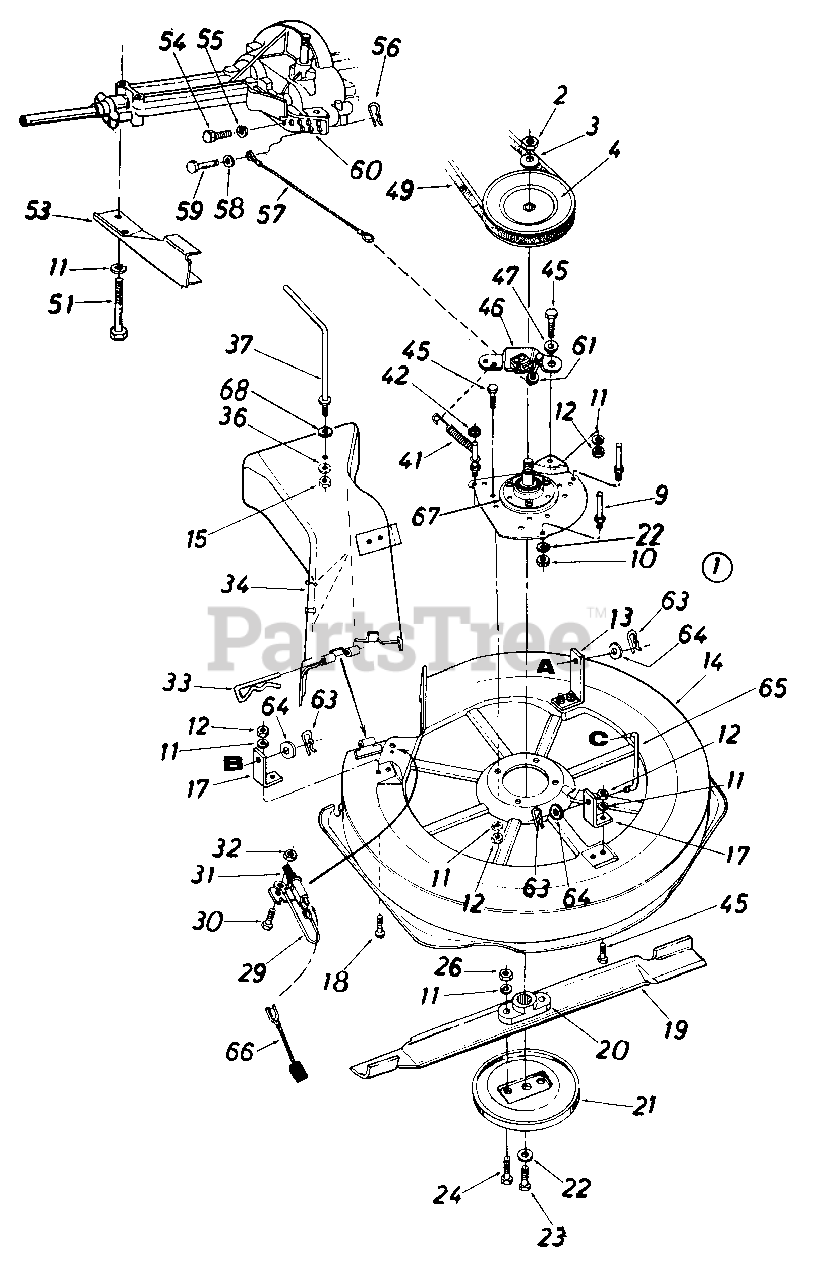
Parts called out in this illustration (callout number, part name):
1	30" R.D. Deck Ass'y. Comp.
2	Hex Jam Nut 5/8-18 Thd.
3	Bell-Wash. .630" I.D. x 1.25"
4	5/8 V-Pulley .75" I.D. x .7"
9	Stud 3/8-16 x 2.75" Lg.
10	Hex Jam Nut 3/8-16 Thd.
11	L-Wash. 5/16" I.D.*
12	Hex Nut 5/16-18 Thd.*
19	30" High Lift Blade
20	Blade Adapter
21	Scalp Plate
22	L-Wash. 3/8" I.D. H.D.
23	Hex Bolt 3/8-24 x 1.0*
24	Hex Bolt 5/16-24 x 1.0" Lg.
26	Hex Nut 5/16-24 Thd.*
29	Electrical Wire
30	Hex Bolt 1/4-20 x .50" Lg.*
31	Safety Switch
32	Hex Nut 1/4-20 Thd.*
33	Internal Cotter Pin
34	R.D. Chute Deflector
36	L-Wash. .32" I.D. x .62" O.D.
37	90ø Rod 5/16-18 Thd.
41	Extension Spring
42	Push Speed Nut
45	Hex Bolt 5/16-18 x .75"
46	Blade Brake Brkt. Ass'y.
47	Shoulder Spacer .500" Dia.
49	"V"-Belt 1/2" x 52" Lg.
51	Hex Bolt 5/16-18 x 2.75n
55	L-Wash. 1/4" I.D.
56	Int. Cot. Pin 5/16" Dia.
57	Brake Cable 9.75" Lg.
58	Fl-Wash. .281" I.D. x .50"
59	Clevis Pin 1/4" Dia.
60	Lower Inside Belt Guard
61	Cap Speed Nut 1/4" Rod
63	Int. Cotter Pin 1/2" Dia.
64	Fl-Wash. .531" I.D. x .930"
65	Deck Link 3.9" Lg.
66	Wire Lead
67	Blade Spindle Ass'y. Comp.
68	Fl-Wash. .344" I.D. x 1.125"
